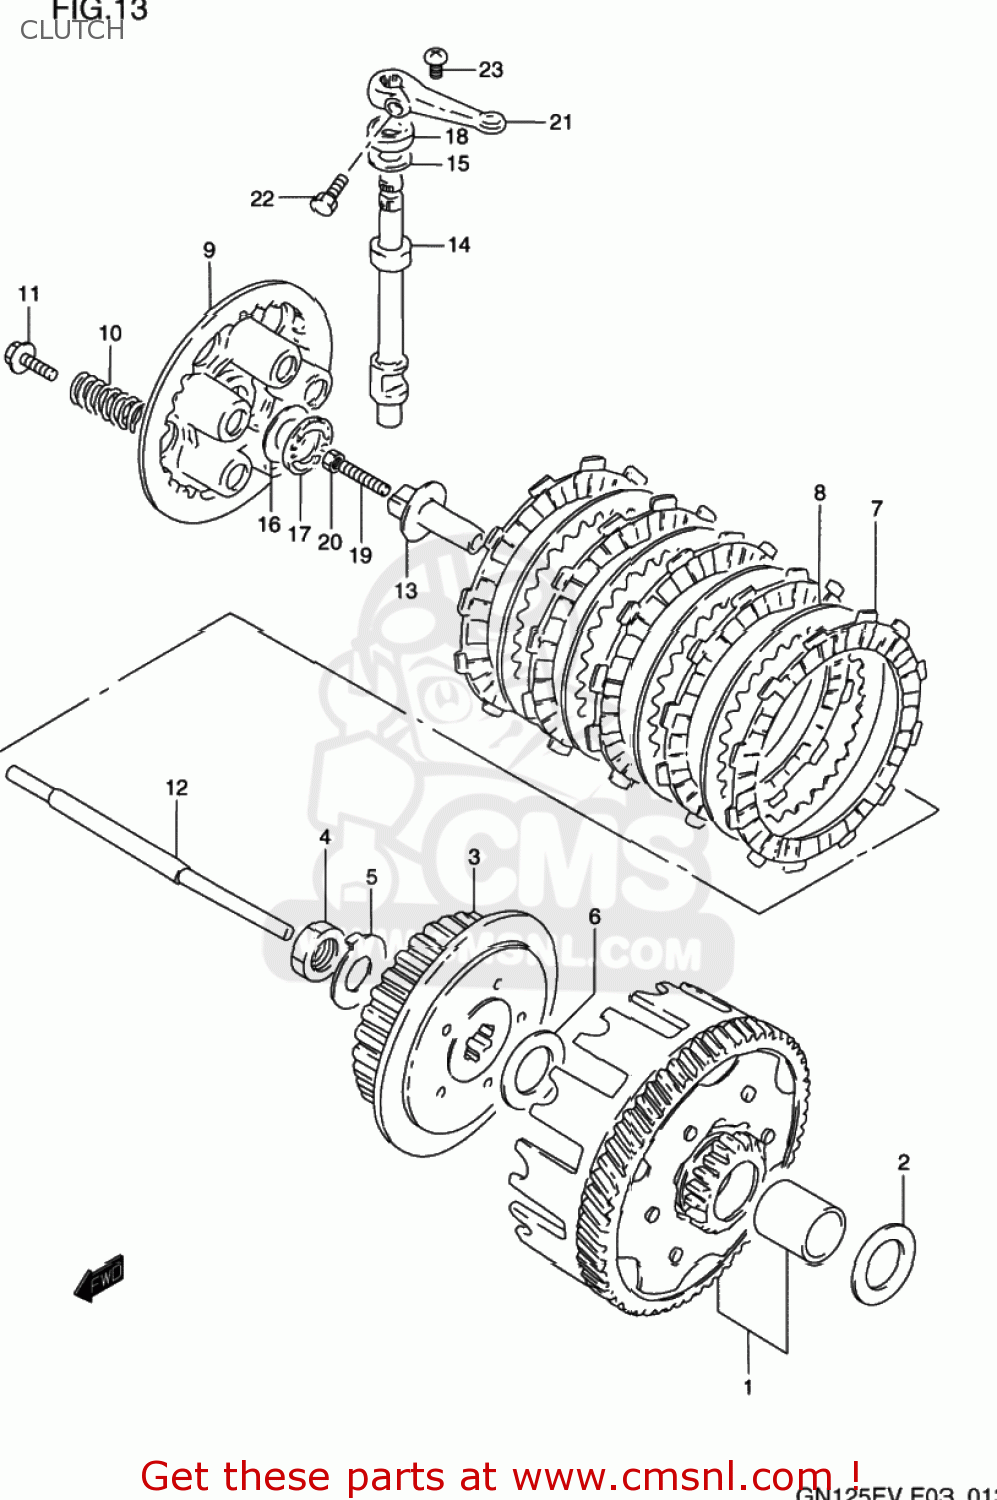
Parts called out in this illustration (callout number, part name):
1	GEAR ASSY,PRIMARY(NT:20/59)
2	WASHER
3	HUB,CLUTCH SLEEVE
4	NUT
5	WASHER
6	WASHER
7	PLATE,CLUTCH DRIVE(T:3.0) (NAS)
8	PLATE,CLUTCH DRIVEN (NAS)
9	PLATE,CLUTCH PRESSURE
10	SPRING
11	BOLT 5X16
12	ROD,CLUTCH PUSH
13	PIECE,CLUTCH PUSH
14	CAMSHAFT,CLUTCH RELEASE
15	WASHER,THRUST
16	WASHER(15.5X28X1)
17	BEARING(15X28X2)
18	SEAL,OIL(10X20X6)
19	SCREW(6X25)
20	NUT
21	ARM,CLUTCH RELEASE
22	BOLT
23	SCREW 6X10
